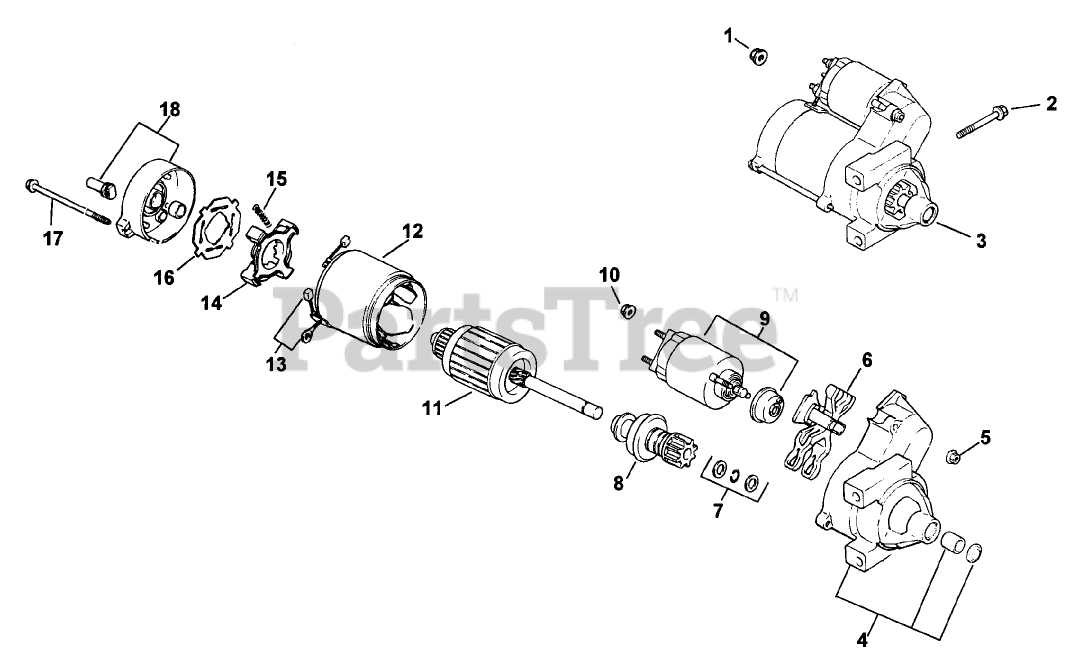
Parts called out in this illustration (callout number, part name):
1	Nut
2	Scew
3	Starter, solenoid shift (Includes 4-18)
4	Cap-Drive End
5	Nut
6	Lever Starter Drive
7	Washer
8	Drive Pinion
9	Solenoid
10	Nut
11	Armature-Starter
12	Frame
13	Kit, brush & spring (Includes 15)
14	Holder-Brush
15	Spring Brush
16	Insulator
17	Bolt
18	Commutator-End Cap
